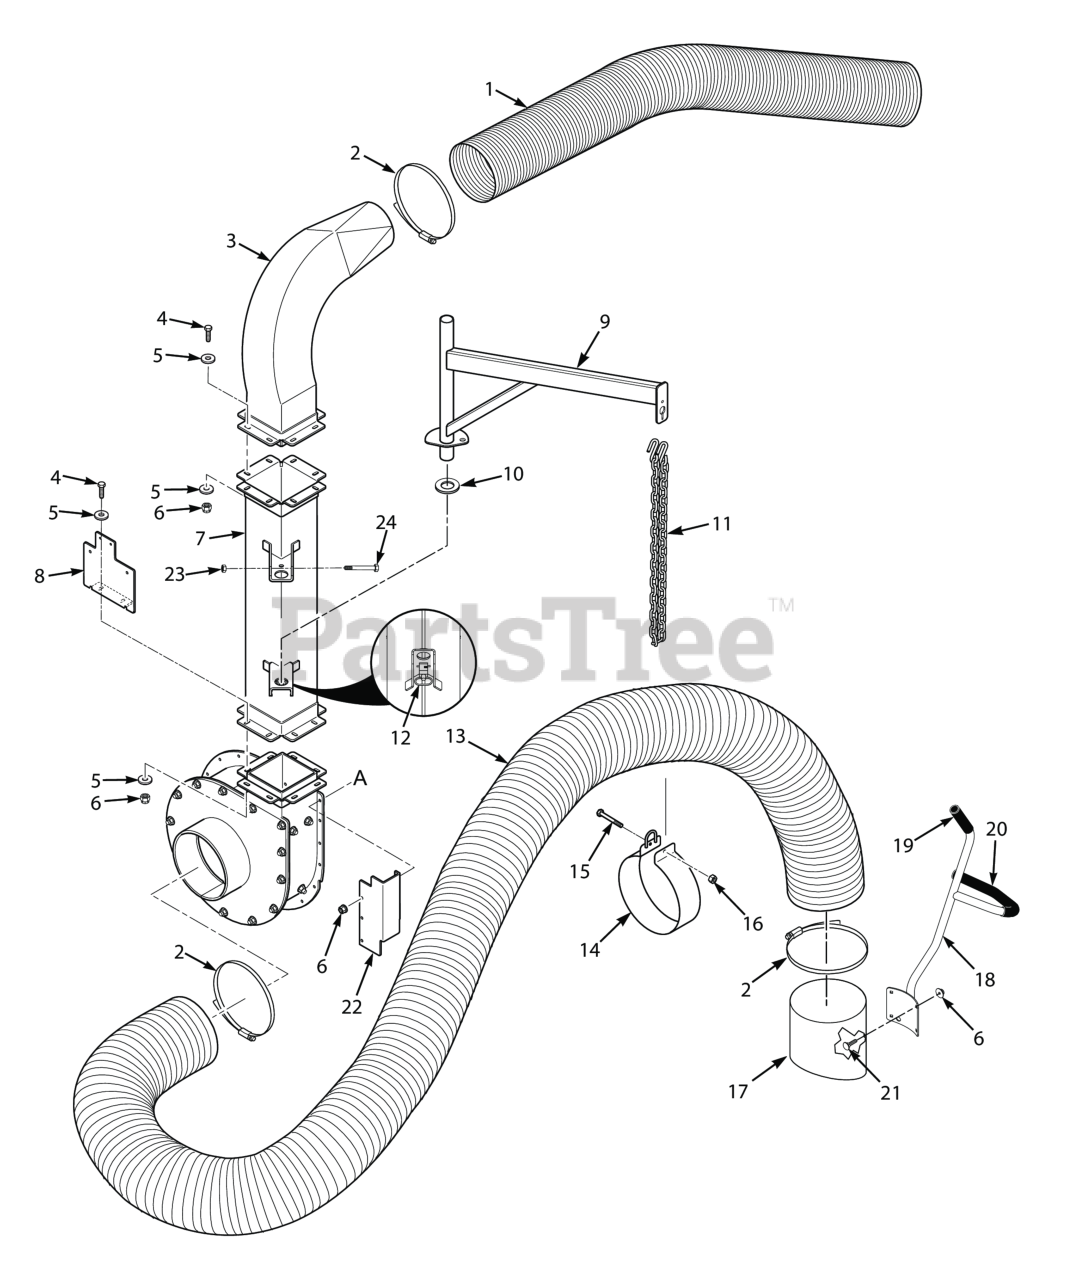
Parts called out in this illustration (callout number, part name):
1	Hose, Clear Poly 8" Dia. x 60"
2	Strap, Ratchet- 66 x 1"
3	Elbow, Exhaust - TL20W
4	Bolt, Hex Head 3/8-16 x 1-1/4", Kawasaki FX / FS
5	Flatwasher, 3/8" Special (.391 x .938 x .105)
6	HEX NUT, ELASTIC STOP LOCK, 3/8-16
7	Discharge Stack w/ Decal - TL20W
8	Bracket, License Plate
9	Boom Weldment
10	Disk, Anti-Friction
11	Chain w/2-Hooks
12	Spring
13	Hose, 12" OD x 120" - .045 w/Wearstrip
14	Band, Hose Support
15	Bolt, Hex Head 5/16-18 x 3-1/2"
16	HEX NUT, ELASTIC STOP LOCK, 5/16-18
17	Nozzle, 12"
18	Handle w/Grips
19	Grip, Handle 1-1/4" x 6"
20	Grip, Handle 1-1/4" x 20"
21	Carriage Bolt, 3/8-16 x 1.0"
22	Bracket, Hose Protector
23	HEX, NUT, ELASTIC STOP LOCK, 1/4-20
24	Bolt, Hex Head 1/4-20 x 4"
